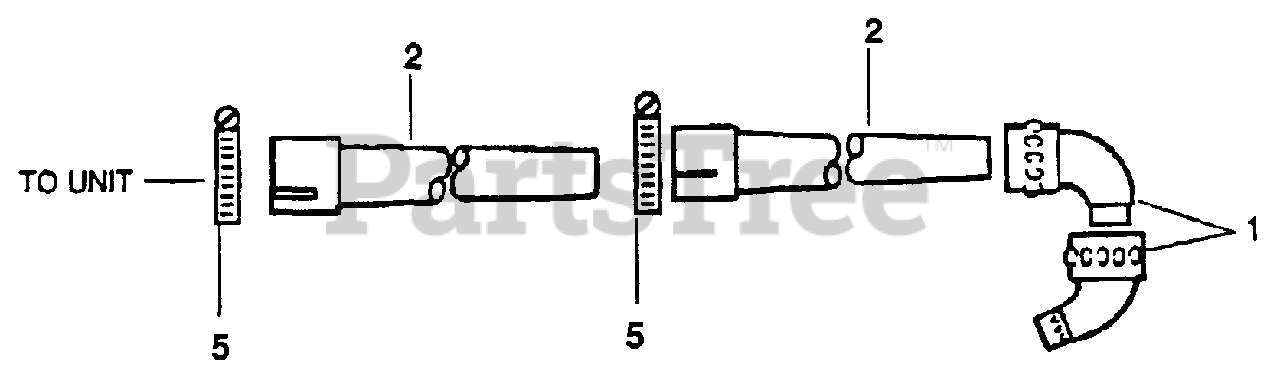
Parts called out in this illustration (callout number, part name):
1	TUBE, BLOWER - ELBOW
2	TUBE, BLOWER - STRAIGHT
5	CLAMP
